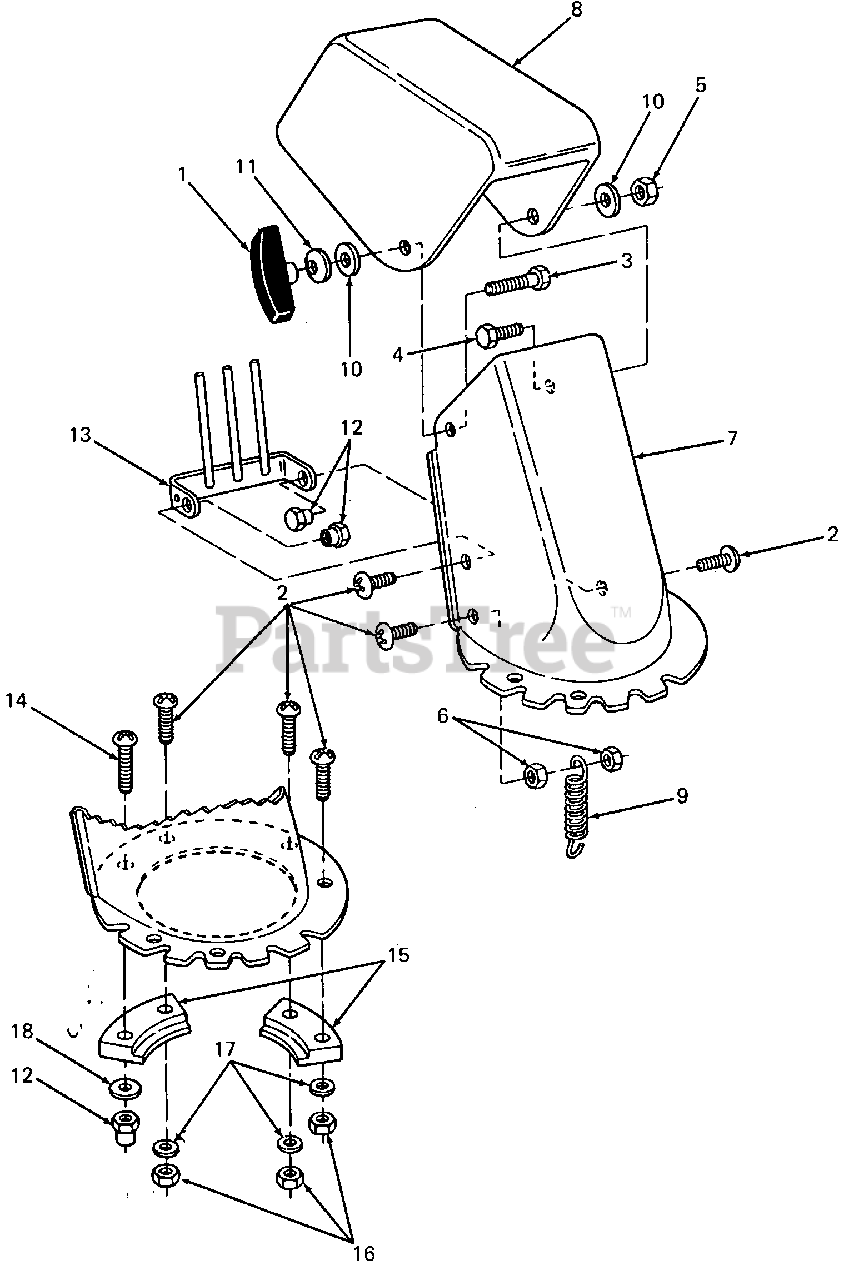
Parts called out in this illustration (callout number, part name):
1	Knob, Handle
2	Screw, Truss Mach, 1/4-20 X .75 Lg
3	Bolt, Carriage, 5/16-18 X 1.0 Lg
4	Screw, Truss Mach, 5/16-18 X .75 Lg
5	Nut, Hex Center Lock, 5/16-18
6	Nut, Hex Center Lock, 1/4-20
7	Chute, 6" Dia Lower
8	Chute, 6" Dia Upper
9	Spring, Extension, .36 OD X 2.5 Lg
10	Washer, Flat, .344 X 1.125 X .063 Thk
11	Washer, Bell, .345 X .88 X .060
12	Nut, Shoulder, 1/4-20
14	Screw, Truss Mach, 1/4-20 X 1.0 Lg
15	Keeper, Chute Flange
16	Nut, Hex Patch Lock, 1/4-20
17	Washer, Flat, .281 X .50 X .063 Thk
18	Washer, Flat, .265 X .93 X .120 Thk
